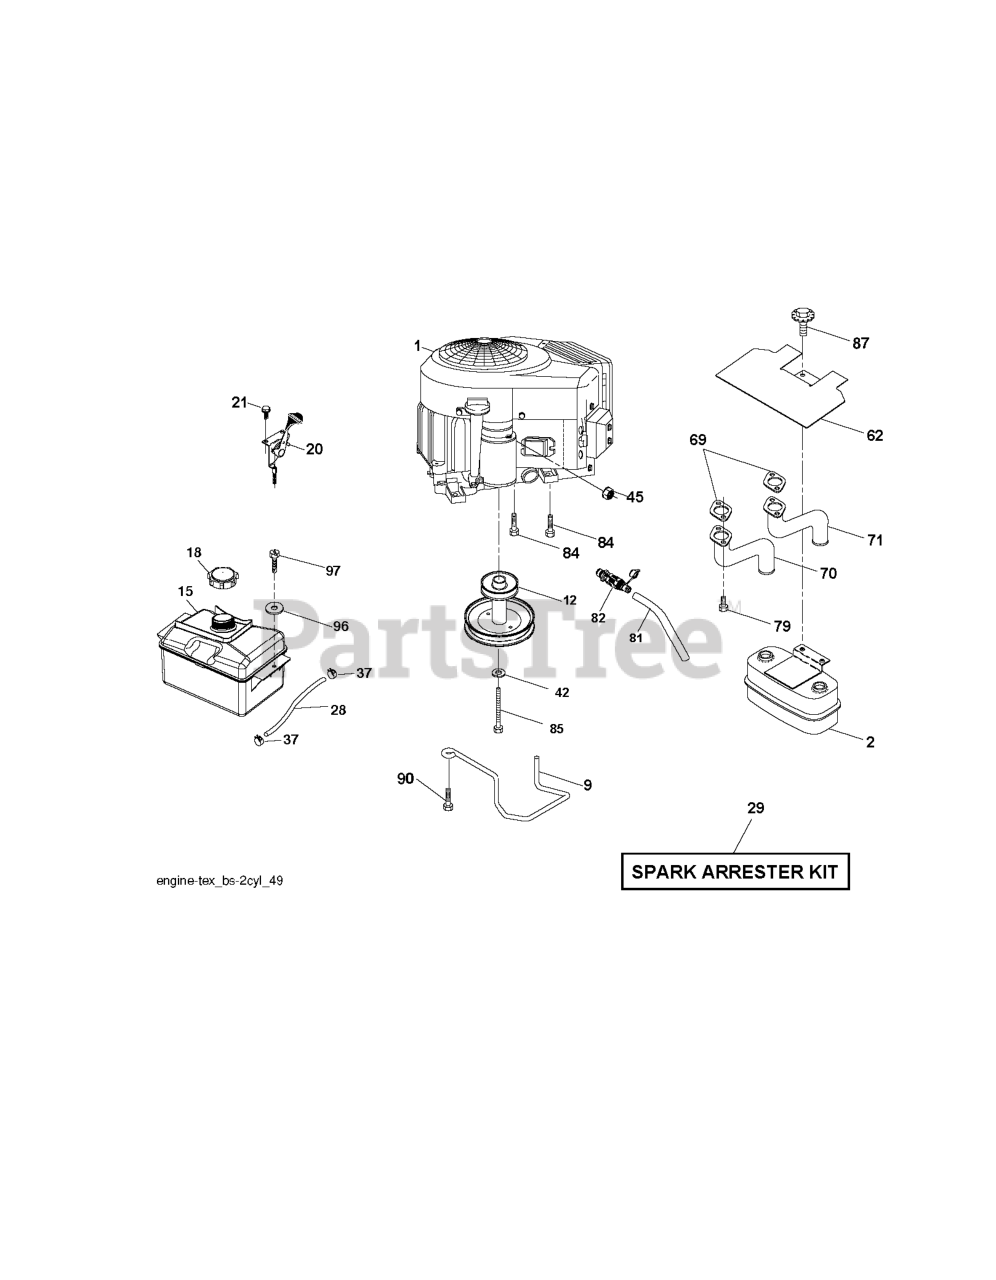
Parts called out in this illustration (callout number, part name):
2	MUFFLER.TWIN.CYL.LOW.TONE
9	KEEPER.BELT.ENGINE.4.2
12	PULLY ENGINE
15	TANK.ASM.FUEL.FR.2.5GA.
18	CAP ASM.FUEL.2.25"FR.
20	CONTROL.TH/CK.COBRA.B&S.TWN.BK
21	SCREW.#10 X 0.750.BOS
28	LINE.FUEL.20"FRONT.EMI
29	KIT.SPARK ARRESTOR 794945 B&S
37	HOSE CLAMP
42	LOCKWASHER
45	NUT
62	RP SHIELD HEAT MUFFLER
69	GASKET.MUFFLER
70	RP.EXHAUST.TUBE.LH.BS/TWIN
71	EXHAUST.TUBE.RH.BS/TWIN
79	SCREW.SOCKET.HEAD.5/16-18
81	TUBE, DRAIN OIL ASM.
82	VALUE.OIL.DRAIN
84	SCREW.3/8-16
85	BOLT HEX 7/16-20X4-1/4"
87	BOLT.5/16-18UNCX3/4 W/SEMS.BLK
90	SCREW 3/8-16X1
97	SCREW HEXWSHR 1/4-20X3/4
